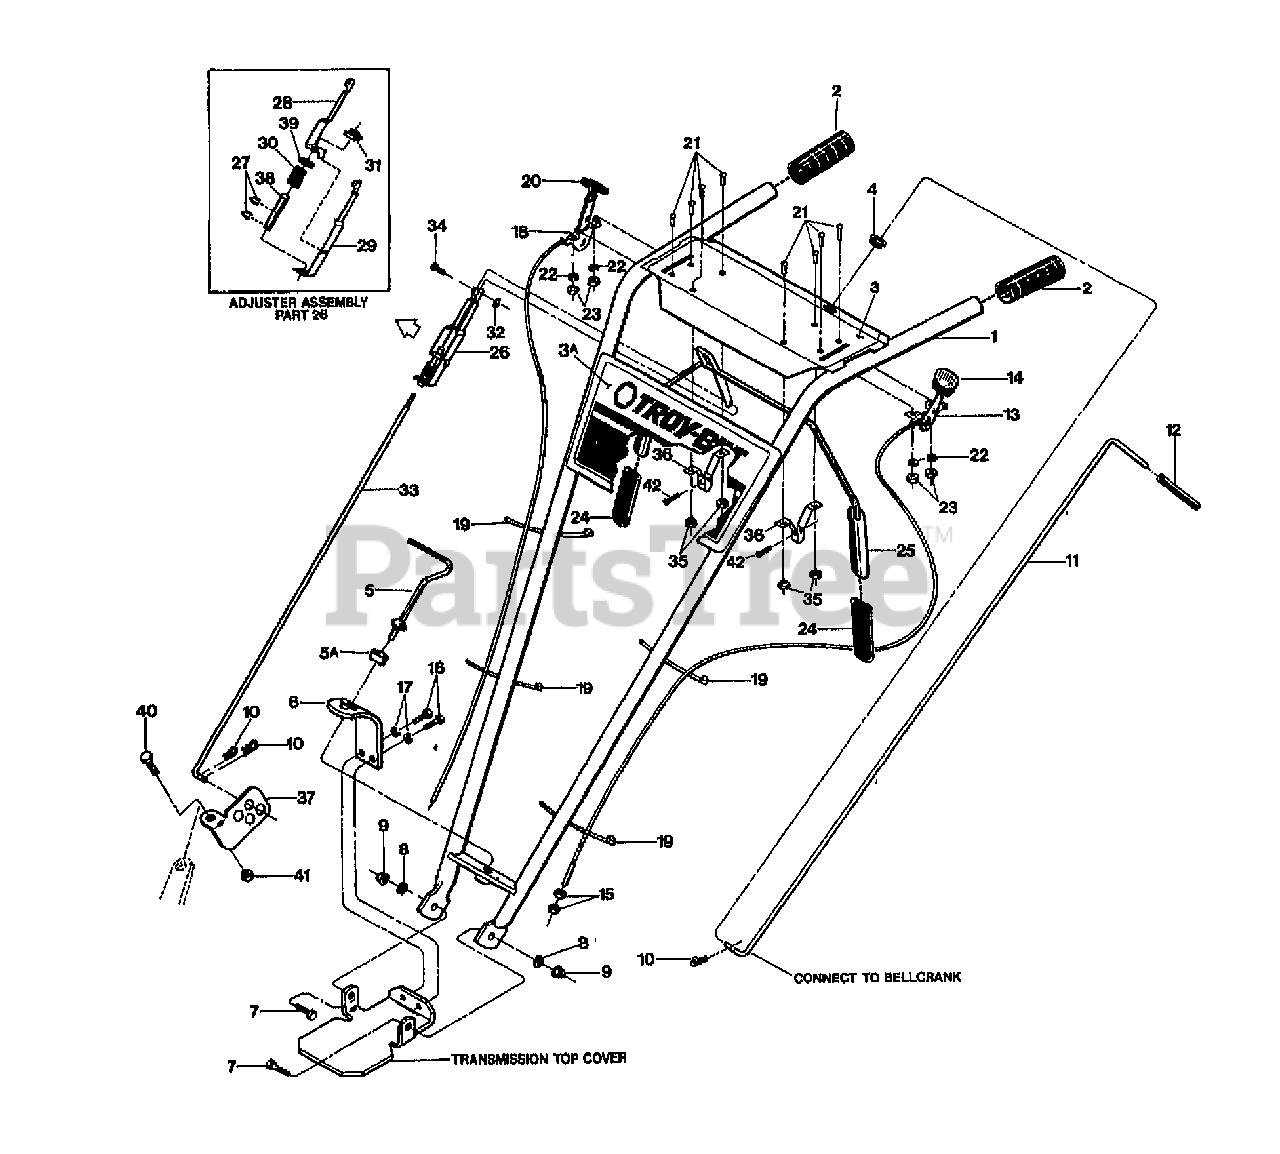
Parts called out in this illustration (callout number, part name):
1	ASSM-HANDLEBAR W/GRIPS (INCL. 2,3,3A,4)
2	GRIP-H/BAR SMOOTH
3	DECAL-CONTROL PANEL
3A	DECAL-GRAPHICS PANEL ECONO
4	BUSHING-NYLON
5	ASSM-STUD H/B
5A	WASHER-1.0X.38X.375
6	PLATE-HANDLEBAR ADJUST
7	SCR-HH 3/8-16X1.0 G5 ZP
8	WASHER-FLAT 3/8 SAE
9	NUT-LOCK 3/8-16 NYLON ZP
10	PIN-CLIP .08
11	ROD-REV W/GRIP OPC (INCL. #12)
12	GRIP-CONTROL ROD
13	CABLE-WHEEL CLUTCH OPC (INCL. 14,15,19,21-23)
14	KNOB-WHEEL DRIVE CABLE
15	NUT-HEX 5/16-24
16	SCR-HH 3/8-16X.75 G5 ZP
17	WASHER-LK .375 @ DEPL
18	CABLE-THROTTLE ECONO OPC (INCL. 20)
19	TIE-RED
20	KNOB-THROTTLE CABLE
21	SCR-RH M10-32X.5 MACH
22	WASHER-LK M10
23	NUT-HH M10-32X.125
24	GRIP-PADDLE SM FRAME OPC
25	BAIL W/GRIPS OPC (INCL. TWO #24)
26	ASSM-ADJUSTMENT OPC (INCL. 27-30,38-39)
27	RING-KLIP .500 ZINC
28	ADJUSTER-RT SIDE OPC
29	ADJUSTER-LT SIDE OPC
30	SPRING-ADJUSTER OPC
31	WELDNUT 5/16-18
32	RING-KLIP .188 DIA
33	ROD-CONTROL OPC
34	ASSM-PIN & CLIP (SMALL FRAME)
35	NUT W/LKWASHER #10-32 ZP
36	BRACKET-BAIL OPC
37	SWIVEL-SMALL FRAME
38	BUSHING-.5X.334X2.88
39	WASHER-.75X.51X.06 ZP
40	SCR-HH 1/4-20X.75 G5 ZP
41	NUT-LK 1/4-20
42	SCR-HWH 1/4-20 X .5 STH
